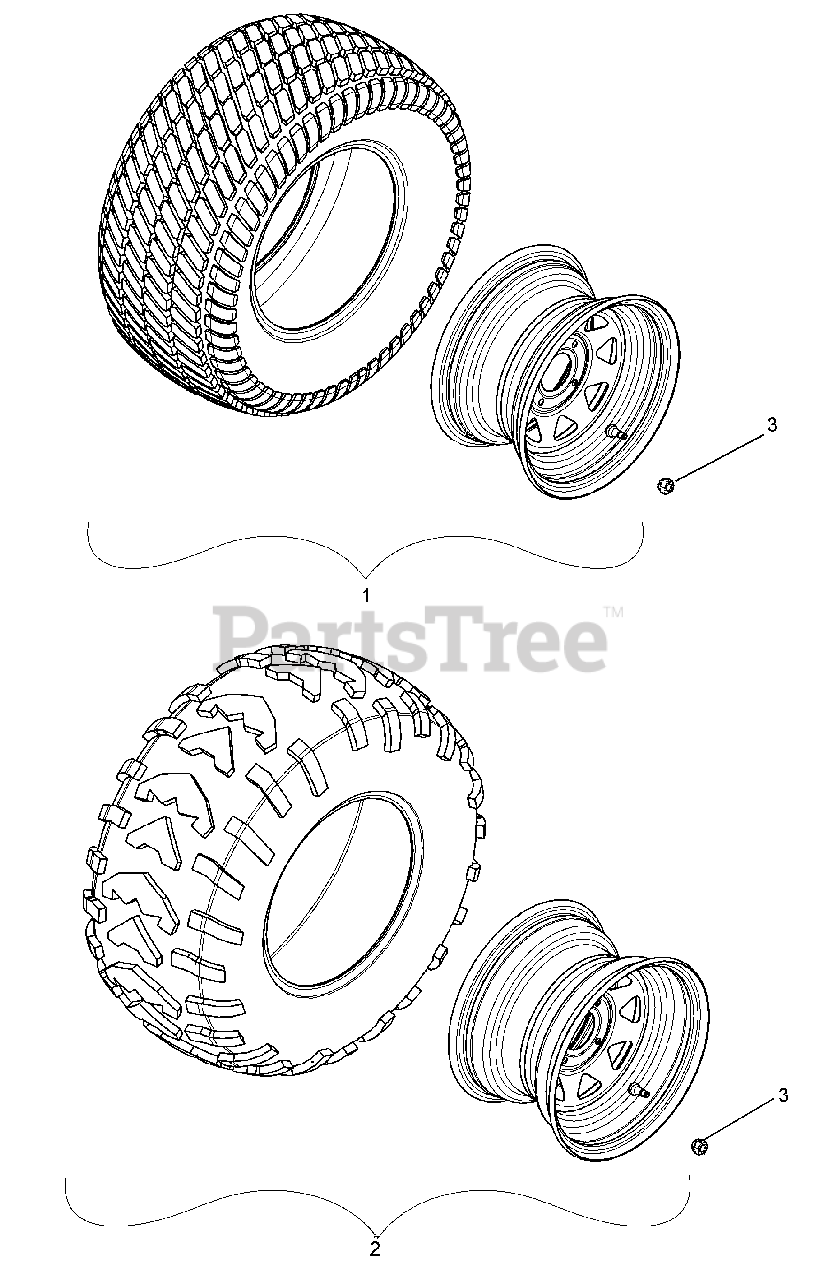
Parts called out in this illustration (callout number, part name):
1	TIRE/WHEEL ASSEMBLY, TREKER TURF REAR (996125)
2	AT TIRE/RIM BLACK RIGHT REAR (996123, 146, 147)
2	AT TIRE/RIM BLACK LEFT REAR (996123, 146, 147)
3	WHEEL NUT .500-20 YZ
